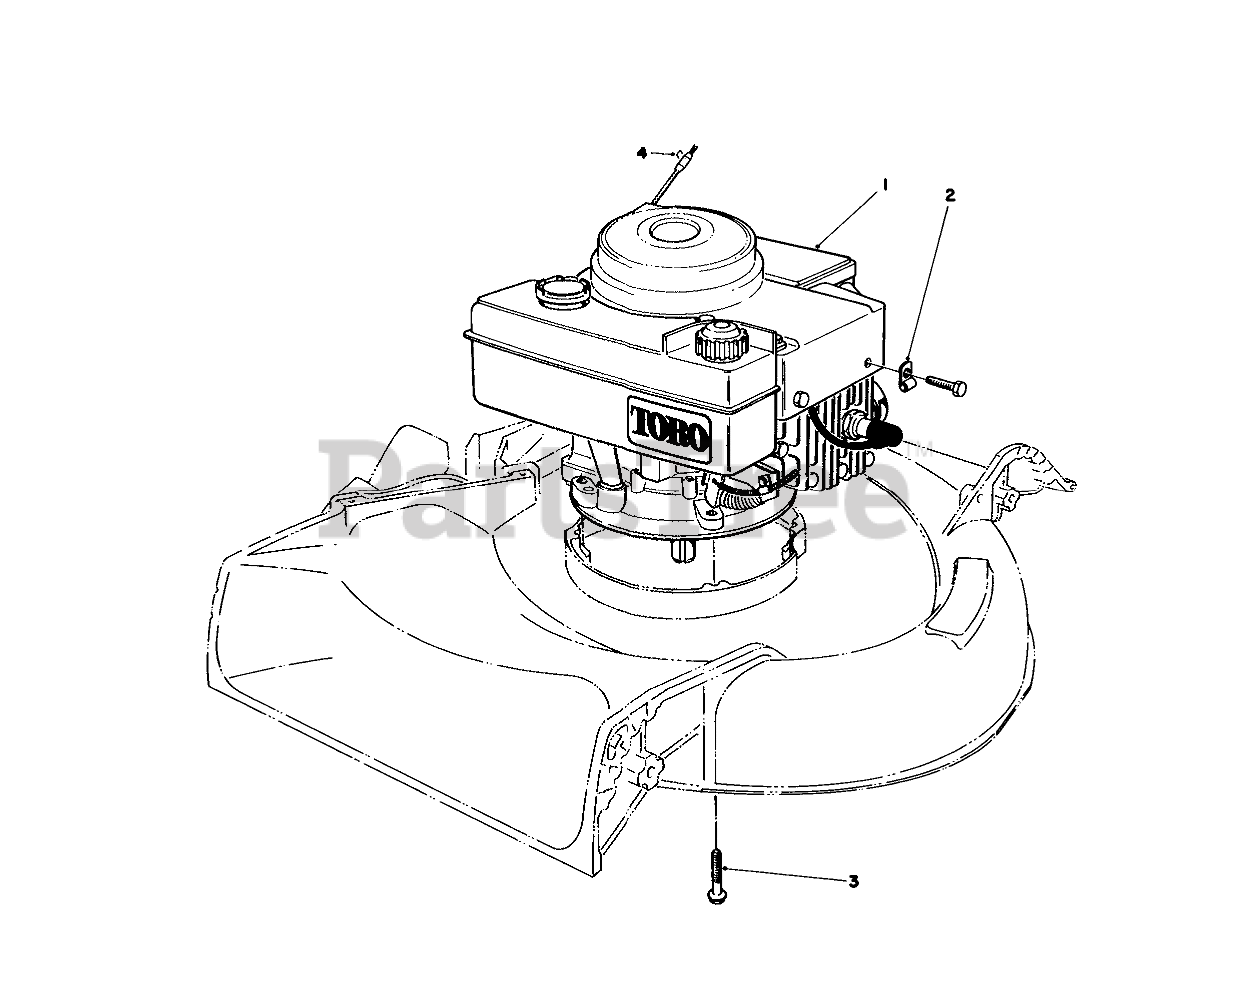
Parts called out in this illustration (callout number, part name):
2	CLAMP
3	3/8-16 X 2-3/4 CAPSCR
4	Staple
